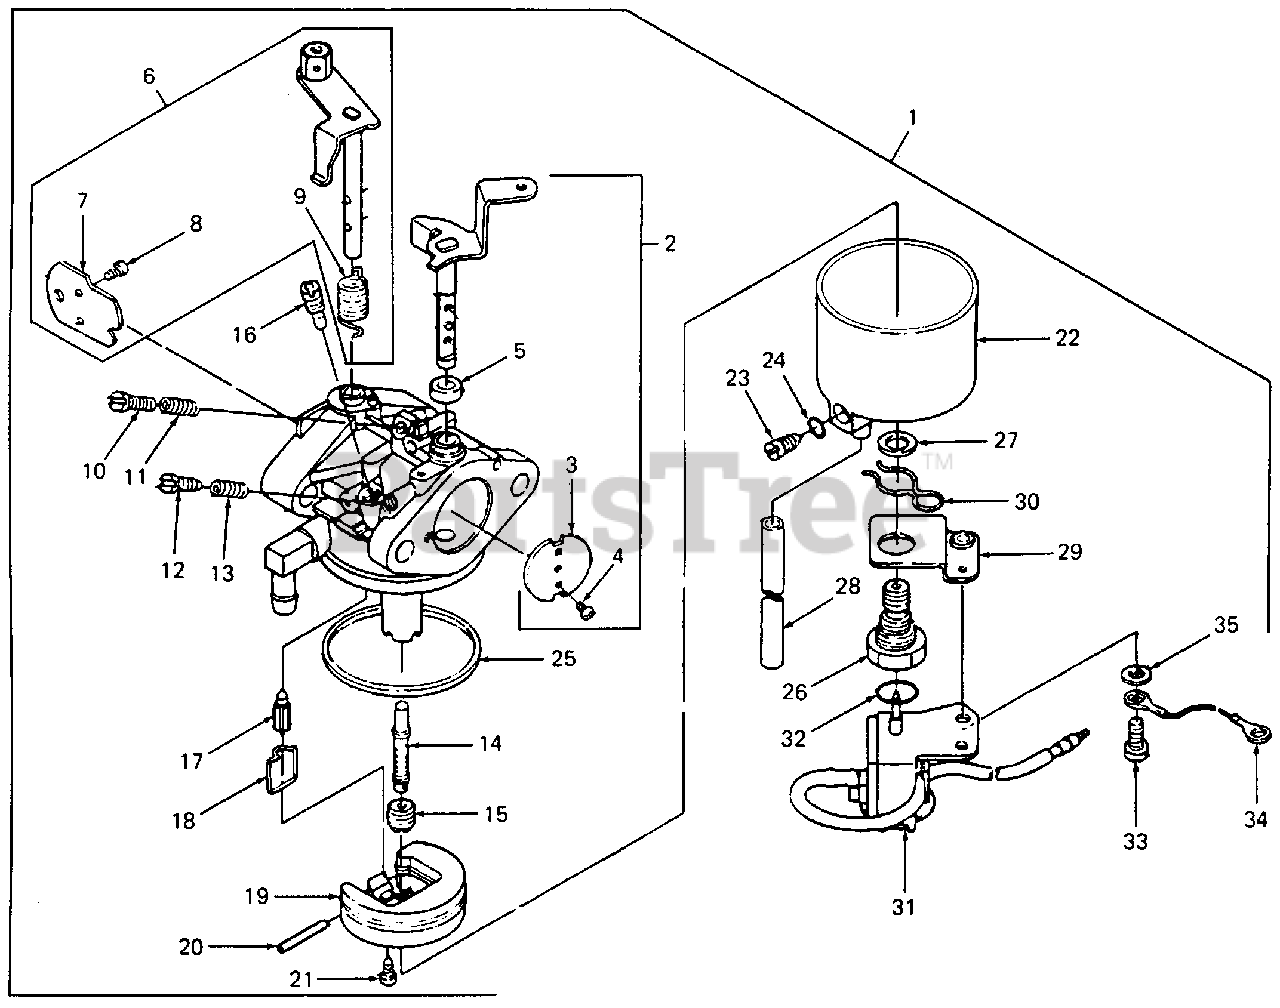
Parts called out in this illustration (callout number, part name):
1	Carburetor Assy
2	Throttle Shaft Assy
3	Valve, Throttle
6	Choke Shaft Assy
9	Spring, Return
10	Screw, Fil Hd
12	Screw, Adjusting
17	Float Valve Assy
22	Chamber, Float
31	Solenoid Valve Assy
33	Screw w/Washer
35	Washer, Plain
